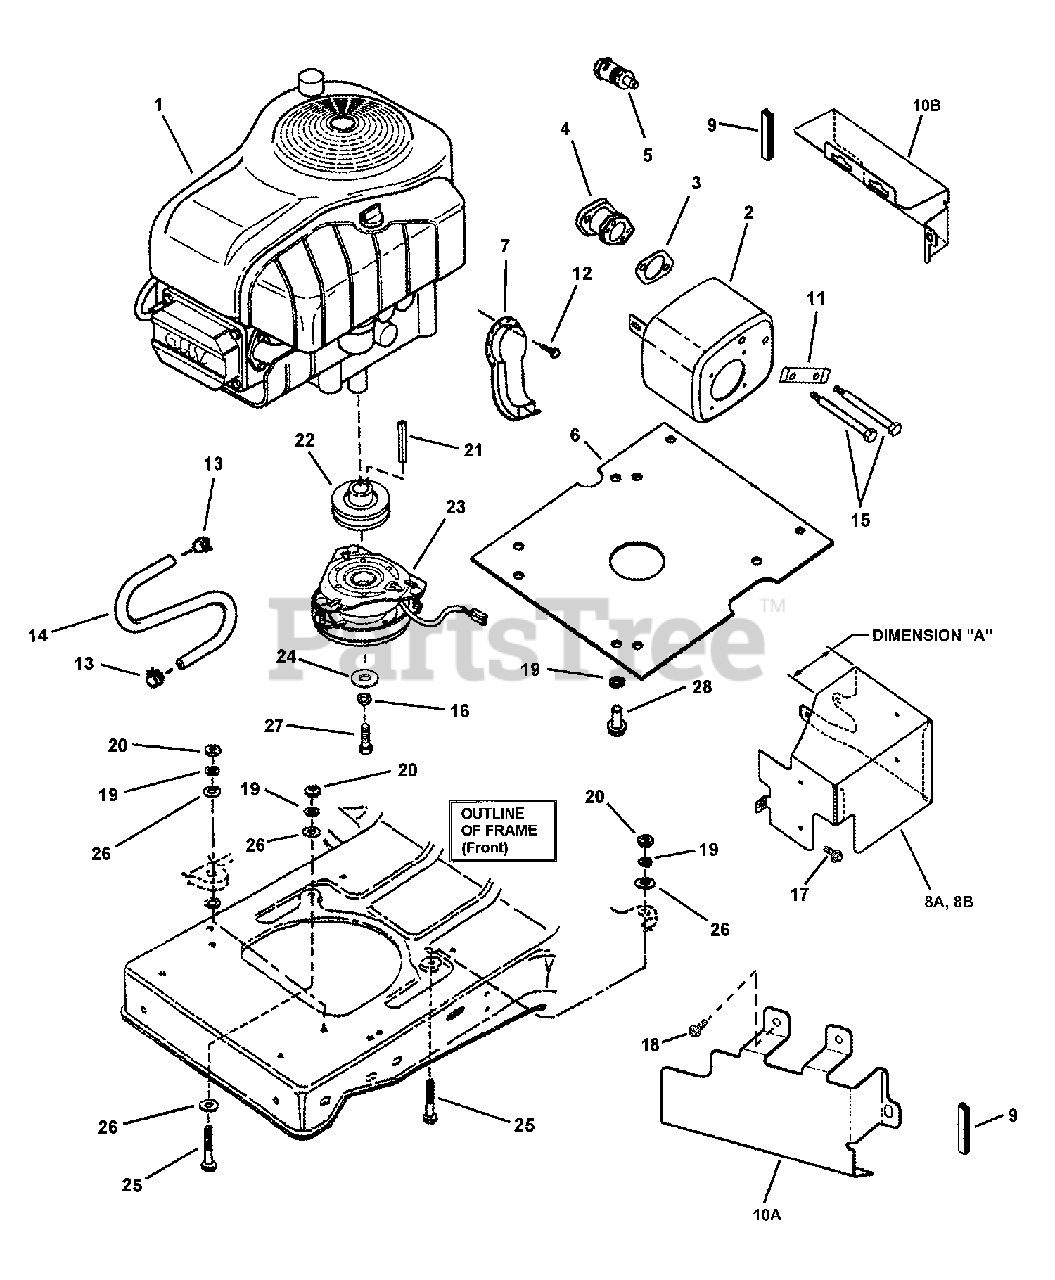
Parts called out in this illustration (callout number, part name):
2	MUFFLER, 14.5HP Briggs Engine
3	GASKET, Exhaust (1.25" I.D.; 1.875" hole centers)
4	ADAPTER, Muffler
5	ASSEMBLY, Oil Valve
6	PLATE, Engine- Briggs Engine
7	WELDMENT, Muffler Deflrctor
8A	WELDMENT, Heat Shield-Muffler- 17HP Intek B&S
8B	HEAT SHIELD, Muffler- 15HP B&S
9	TRIM-Heat Shield (3" long)
10A	HEAT SHIELD, Manifold 17HP B&S
10B	HEAT SHIELD, Manifold 15HP B&S
11	SCREW LOCK
12	SCREW, #8-18 x 1/2" Hex Head Sheet Metal
13	CLAMP, .490 x .31
14	FUEL LINE, 29" long
15	SHOULDER BOLT, 5/16-18 thread x 4"
16	WASHER, 7/16" Split Lock
17	SCREW, 1/4-20 x 1/2" Hex Washer Self-Tap
18	SCREW, 1/4-20 x 1/2" Hex Flange Lock
19	WASHER, 5/16" Split Lock
20	NUT, 5/16-18 Hex, GR 5 or B
21	KEY, 1/4 Square x 1-3/4"
22	PULLEY, Traction Drive 42&48 TT K46
23	ELECTRIC CLUTCH, Ogura MA-GT-DX11CU (Series "I")
24	WASHER, 7/16 I.D. x 1-1/2" O.D. x .188 thick
25	BOLT, 5/16-18 x 1-3/4" Hex Flange Lock, GR 5
26	WASHER, 5/16" Flat
27	SCREW, 7/16-20 x 2-1/2" (Special), GR 5
28	SCREW, 3/8-16 x 1" Hex Washer Self-Tap
